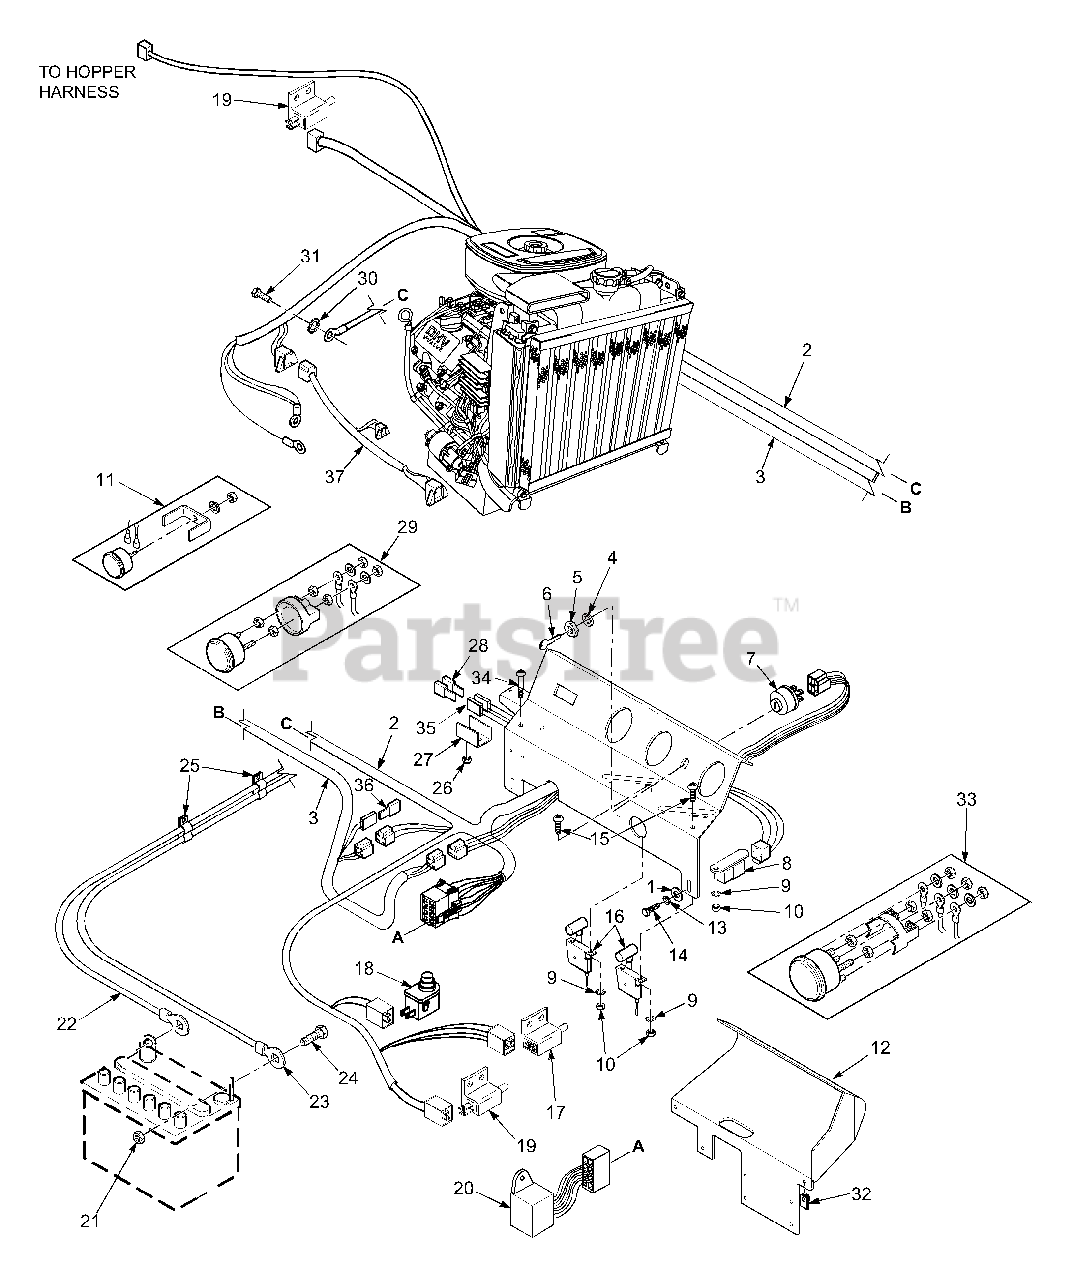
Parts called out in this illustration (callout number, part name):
1	Flatwasher, 5/16-.375 x .875 x .083
2	Wire Harness, SCR
3	Wire Harness, Hopper
4	Lockwasher, Internal 5/8"
5	Nut, 5/8-32 Special
6	Key & Ring
7	Keyswitch w/hardware
8	Relay
9	Lockwasher, #10 external tooth
10	Nut, #10-32 UNF
11	Hour Meter
12	Instrument Panel, Lower
13	Lockwasher, 5/16
14	Bolt, Hex Head 5/16-18 x 1"
15	Screw, #10-32 x 1/2"
16	Control Cable
17	Switch, PTO
18	Switch, Seat
19	Switch, Brake & Hopper
20	Interlock Module
21	Nut, 1/4-20
22	Battery Cable, Black
23	Battery Cable, Red
24	Bolt, Hex Head 1/4-20 x 1/2"
25	Cable Clamp, Double
26	Nut, Elastic Stop #10
27	Bracket, Fuse Holder
28	Fuse, 20 Amp
29	Ammeter
30	Lockwasher, 3/8"
31	Bolt, Hex Head
32	U-Nut, 5/16-18
33	Water Temp Gauge
34	Screw, #10-32 x 1-1/2"
35	Fuse Holder W/Fuse & Connector
36	Fuse, 15 Amp
37	Wire Harness, Engine SCR 27KA
